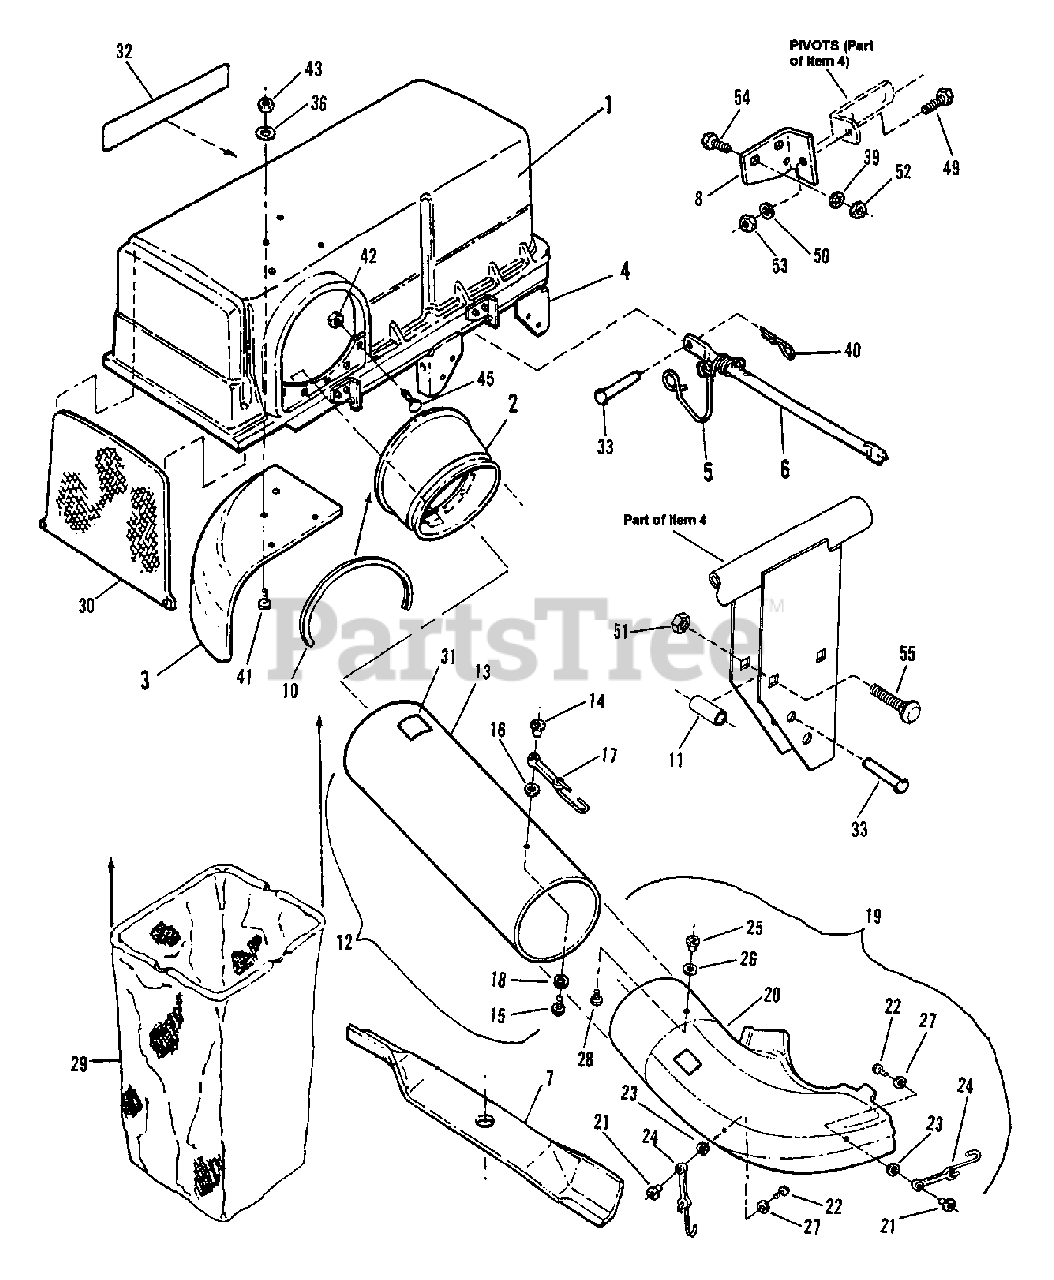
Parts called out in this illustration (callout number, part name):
1	COVER Assembly
2	INLET
3	SECTOR (Inside top baffle)
4	MOUNTING Assembly
5	SPRING & Hook Assembly
6	BRACE
7	ASSEMBLY, Blade
8	HINGE, Top
10	SEAL
11	PAD, Bumper
12	ASSEMBLY, Tube/Strap
13	TUBE, Grass
14	NUT, #10-24 Weld
15	SCREW, #10-24 x 5/8" Pan Head
16	WASHER, 3/16 Flat
17	ASSEMBLY, Strap Mounting
18	WASHER, 7/32 Flat
19	ASSEMBLY, Adapter/Strap
20	ADAPTER
21	NUT, #10-24 Weld
22	SCREW, #10-24 x 5/8" Pan Head
23	WASHER, 3/16 Flat
24	ASSEMBLY, Strap Mounting
25	NUT, 5/16-18 "T"
26	WASHER, 11/32 Flat
27	WASHER, 7/32 Flat
28	SCREW, 5/16-18 x 5/8" Pan Head
29	ASSEMBLY, Bag
30	ASSEMBLY, Screen
31	DECAL, Caution
32	DECAL, SNAPPER
33	PIN, 5/16 x 11/16" Clevis
36	WASHER, 1/4 Flat (Grade 5)
39	WASHER, 1/4 Internal Tooth Lock
40	PIN, 3/32 x 1-1/2" Hair
41	BOLT, 1/4-20 x 3/4" Short Neck Carriage, Grade 5
42	NUT, 1/4-20 Flange Lock
43	NUT, 1/4-20 Hex, Grade 5 or B
45	BOLT, 1/4-20 x 1/2" Short Neck Carriage, Grade 5
49	SCREW, 5/16-24 x 1" Hex Head Cap, Grade 5
50	WASHER, 5/16 "Split Lock
51	NUT, 5/16-18 Hex Center Lock
52	NUT, 1/4-28 Hex, Grade 5 or B
53	NUT, 5/16-24 Hex Center Lock
54	SCREW, 1/4-28 x 3/4" Hex Head Cap
55	BOLT, 5/16-18 x 1-1/2" Carriage, Grade 5
